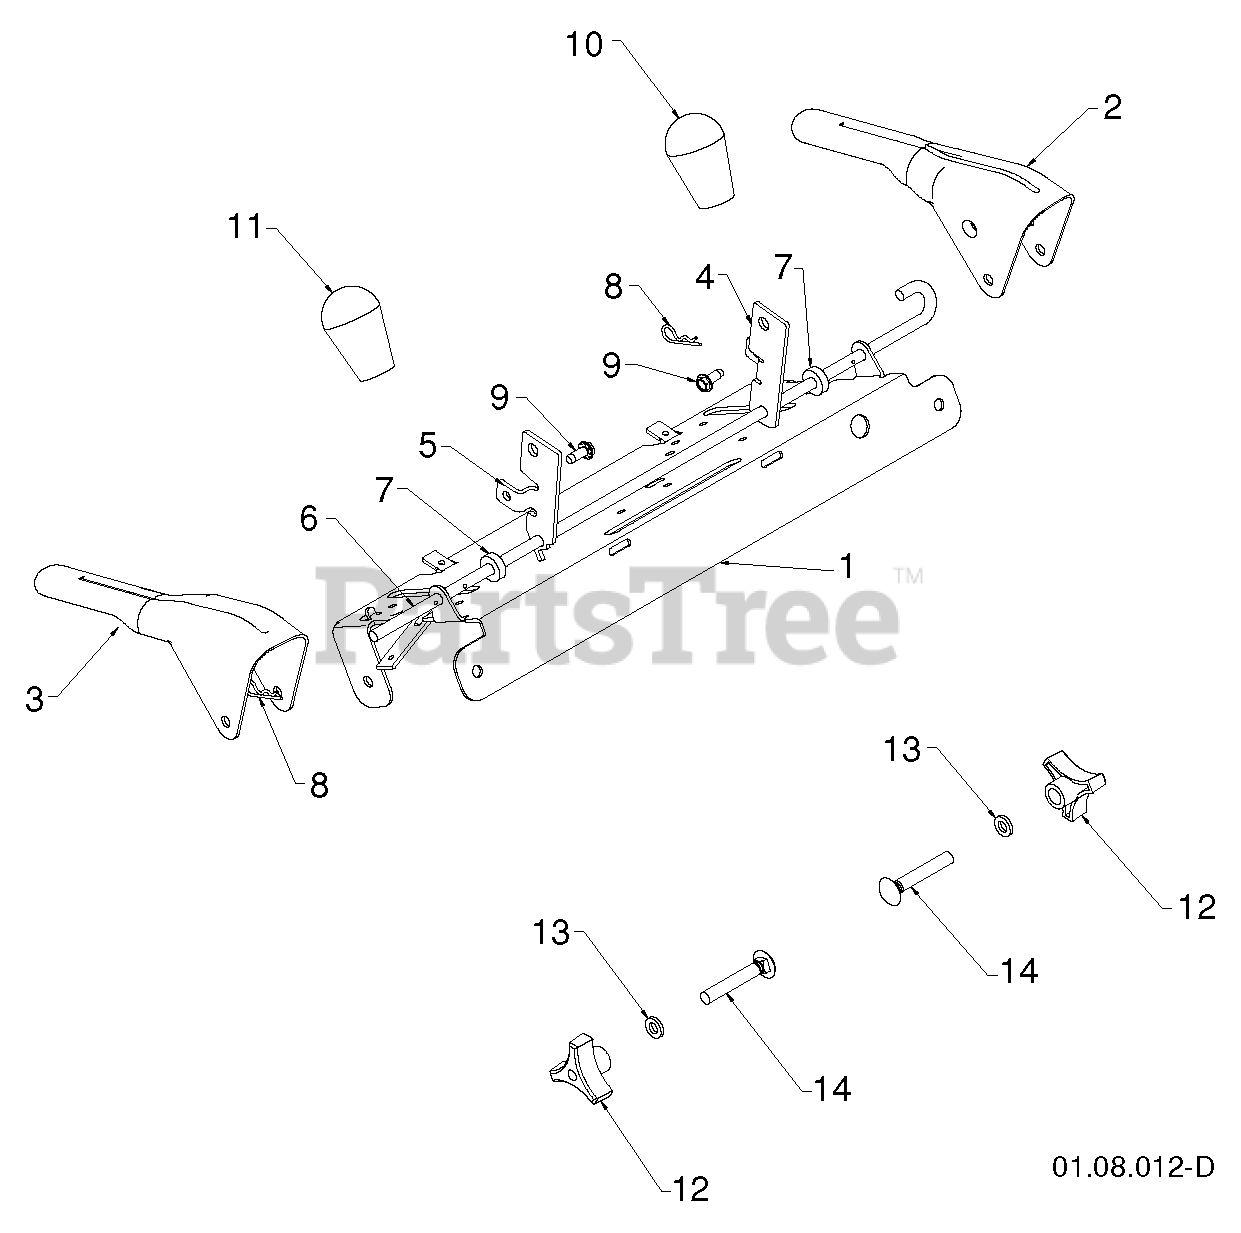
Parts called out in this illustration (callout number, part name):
1	CONTROL PANEL
2	CONTROL LEVER LH
3	RP.LEVER.CONTROL.RH.PNT.BLACK
4	TRACTION ROD ARM
5	ARM.IMPELLER.ROD.
6	BAIL.CONTROL.INTERLOCK
7	SPACER.CONTROL.LEVER
8	RETAINER
9	SCREW 14-20 X 5/8
10	KNOB LEVER, BLACK
11	RED KNOB SHIFTER
12	KNOB.HANDLE.3/8.TRI-POINT.BLAC
13	WASHER
14	BOLT 3/8-16 X 2-1/4
